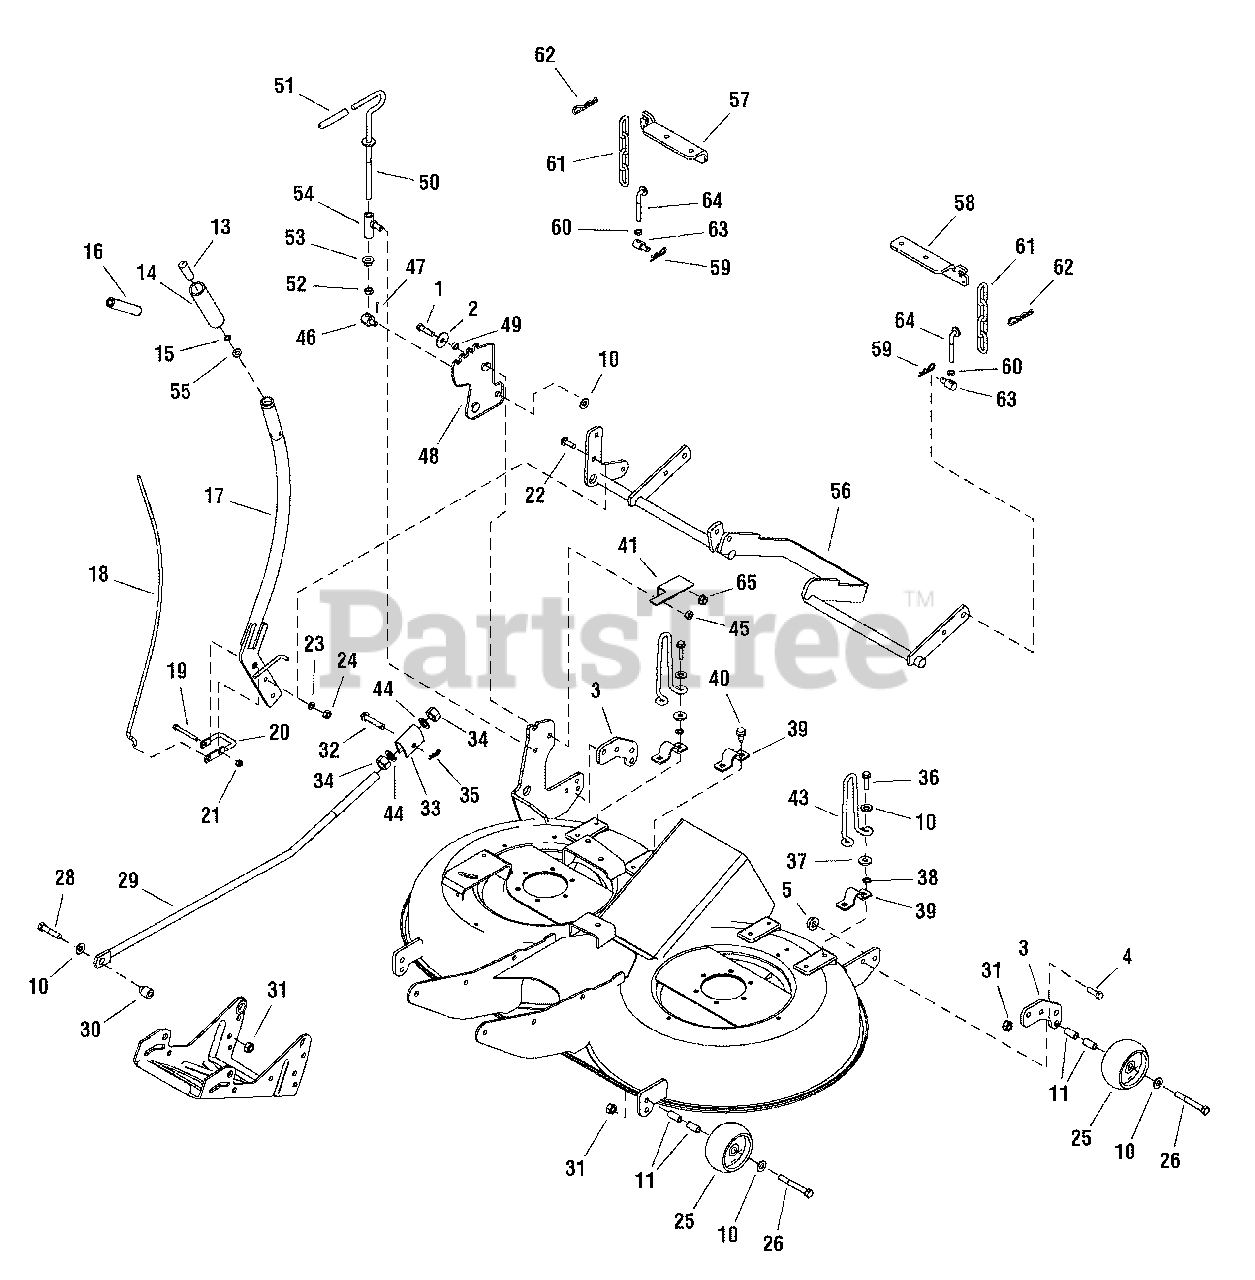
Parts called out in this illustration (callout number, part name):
1	CAPSCREW, Hex Head, 5/16-18 x 1 1/4
2	WASHER, 5/16
3	BRACKET, Flat Mounting
4	CAPSCREW, Hex Head, 5/16-18 x 1
5	NUT, Hex Flange 5/16-18 Esna
10	WASHER, 3/8
15	NUT, Push Pal 1/4 Diameter Thread
16	SPRING, Compression
17	HANDLE ASSEMBLY, Lift Curved
18	ROD, Curved
19	CAPSCREW, Hex Head 1/4-20 x 2-1/4 G5
21	NUT, Hex Lock Esna Light 1/4-20
22	BOLT, Carriage, Short Neck, 5/16-18 x 1
23	LOCKWASHER, Spring 5/16
24	NUT, Hex 5/16-18
26	CAPSCREW, Hex Head 3/8-16 x 3 G5
28	CAPSCREW, Hex Head, 3/8-16 x 1-3/4
30	SPACER, 3/8 x 3/4 x 15/16
31	NUT, Hex Flange, 3/8-16
32	PIN, Round Head Drilled 3/8 x 2
33	TRUNNION
34	NUT, Hex 5/8-11
35	PIN, Quick
36	SCREW, Hex Washer Head Taptite 5/16-18 x 1-1/4
37	WASHER, 5/16
38	NUT, Push Pal 5/16 Diameter Thread
39	STRAP
40	SCREW, Hex Washer Head Taptite 5/16-18 x 3/4
41	BRACKET, Height of Cut
44	WASHER, 5/8
45	NUT, Hex Lock Esna Light 5/6-18
46	PIVOT, 3/4 Hex & 3/8
47	COTTER PIN,
48	BRACKET, Adjusting
50	ROD & WASHER ASSEMBLY
51	GRIP
52	NUT, Hex Jam 3/8-16
53	NUT, Hex Flange 3/8-16
54	GUIDE ASSEMBLY, Rod
55	WASHER, 5/16
56	SHAFT ASSEMBLY, Rocker 40"
57	HANGER, R.H.
58	HANGER, L.H.
59	CLIP, Hair Pin
60	NUT, Hex Jam 5/16-18
61	CHAIN, Link
62	CLIP, Hair Pin
64	ROD, Height Adjusting
65	NUT, Hex Flange 3/8-16 Two-Way Lock
